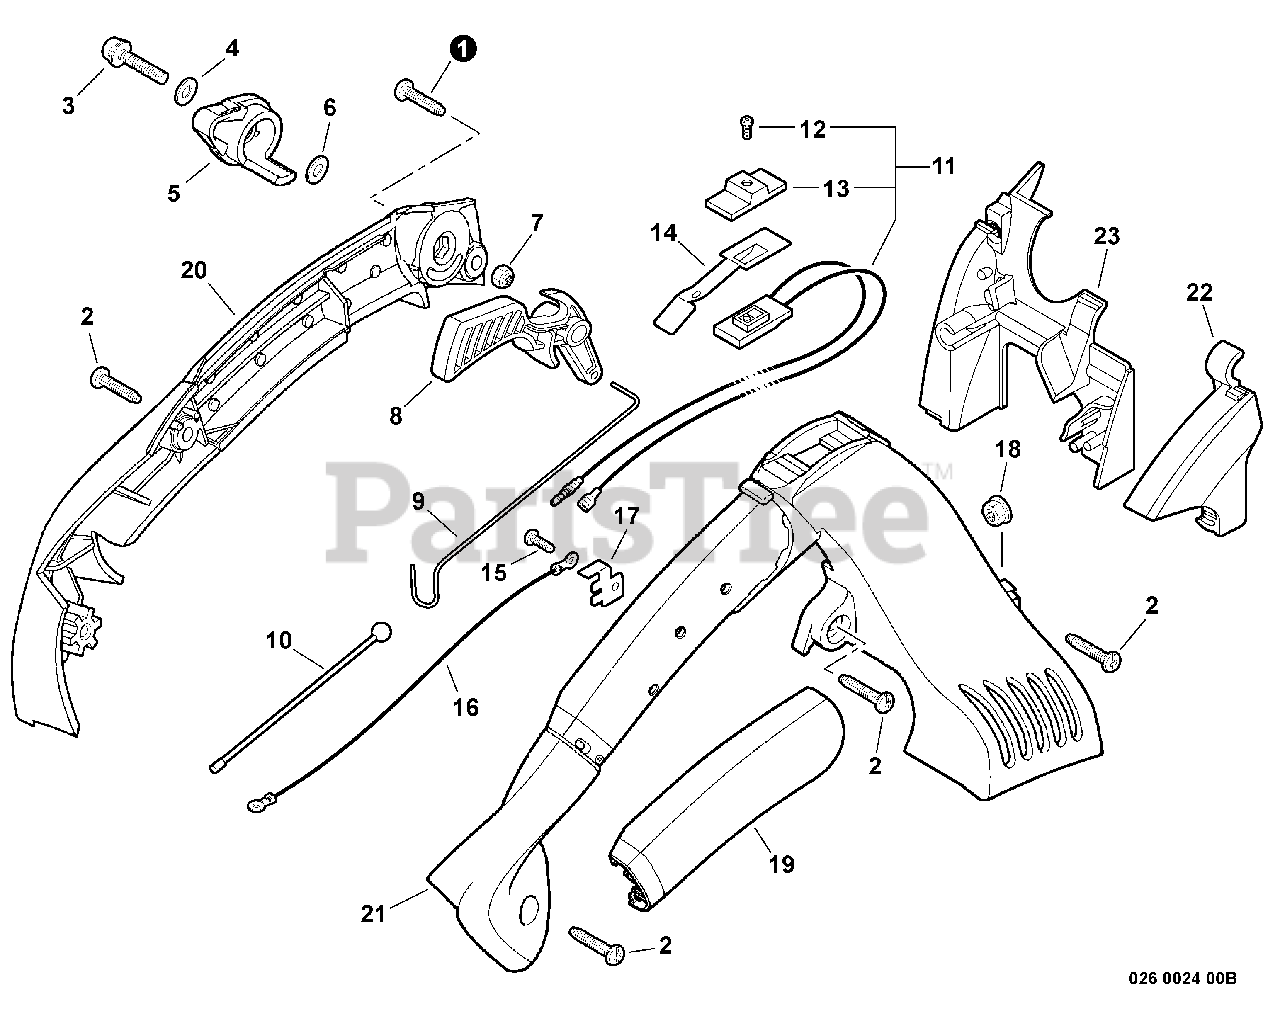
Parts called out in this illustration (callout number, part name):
1	SCREW 5×25
2	SCREW, TAPPING 5×20
3	SCREW 5×25
4	WASHER 5.3×10×1
5	LEVER, THROTTLE
6	WASHER 5.5×12×0.8
7	NUT, LOCK M5
8	TRIGGER, THROTTLE
9	ROD, THROTTLE
10	CABLE, THROTTLE
11	SWITCH ASSY, ON-OFF
12	SCREW 3×10
13	KNOB, SWITCH - ORANGE
14	TERMINAL
15	SCREW 4×10
16	LEAD - GROUND
17	TERMINAL, GROUND
18	NUT, FLANGE M5
19	GRIP, HANDLE
20	HANDLE, CONTROL - LEFT
21	HANDLE, CONTROL - RIGHT
22	COVER, THROTTLE
23	COVER, CYLINDER - PLASTIC
